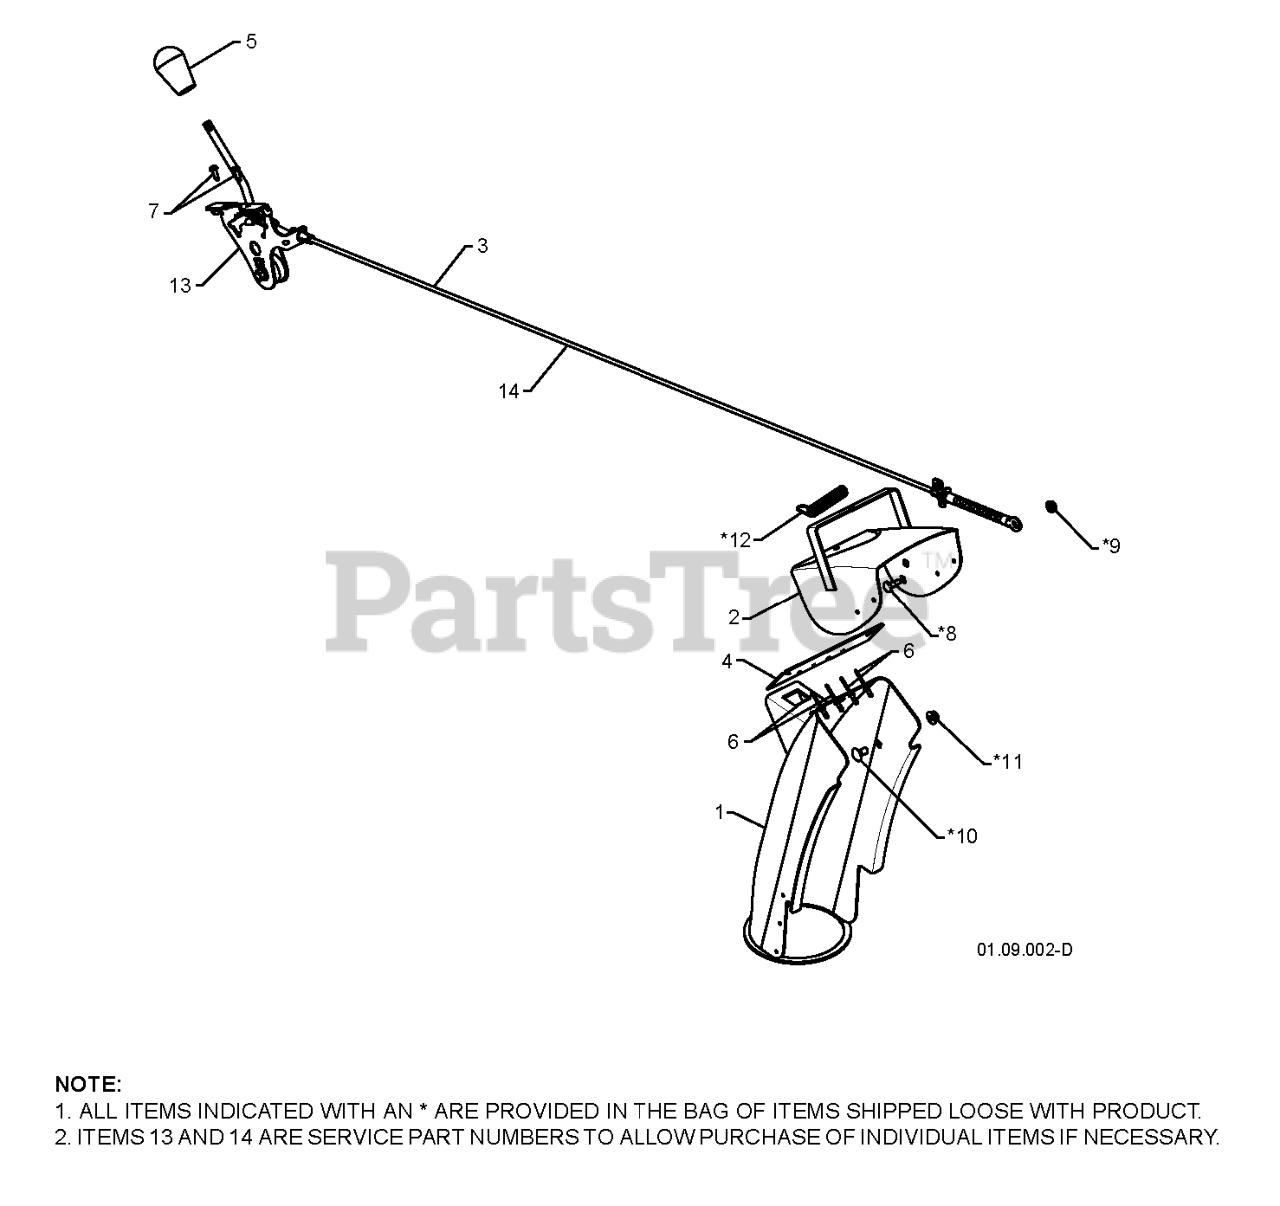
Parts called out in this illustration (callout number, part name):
1	CHUTE.WELDMENT
2	DEFLECTOR.WELDMENT.PNT.ORANGE
3	RP.CONTROL.ASM.DEFLECTOR.SNOW
4	SEAL.DEFLECTOR
5	KNOB LEVER, BLACK
6	RIVET BLIND
7	SCREW #10-24 X 5/8
13	RP CNTRL.HEAD.ASSEM.DEFLECTOR
14	RB SERVICE.CHUTE.DEF.CBL.BLK
